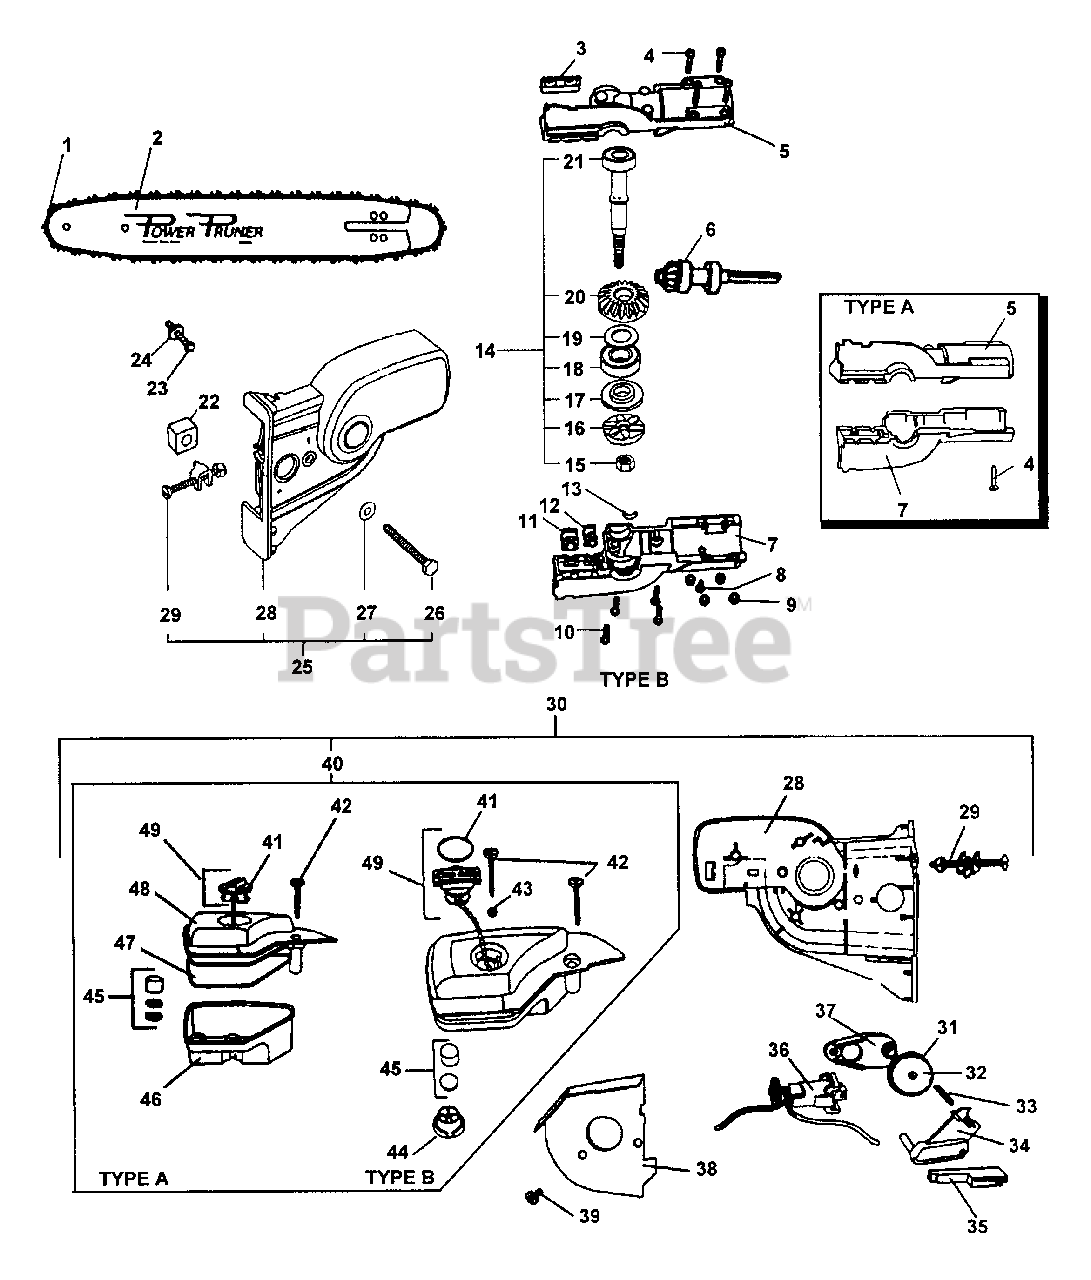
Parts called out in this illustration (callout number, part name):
1	SAWING CHAIN - 90SG -- 10"
2	GUIDE BAR - 10" -- 90VS
4	SCREW, TORX 10-24 UNC 1-1/4
5	CASE, GEAR
6	SHAFT GEAR ASSY
7	CASE, GEAR
8	SCREW
9	NUT, LOCK 10-24 UNC
10	SCREW, TORX
11	SPACER
14	GEAR SHAFT ASSY
15	NUT, HEX
16	SPROCKET DRIVE
17	SPACER, SPROCKET
18	BEARING, BALL 6001 DDU
19	WASHER 12
20	GEAR, BEVEL
21	SHAFT, GEAR
22	SPACER
23	SCREW
24	WASHER 6
25	OILER COVER ASSY
27	WASHER, FLAT
28	COVER, OILER
29	TENSIONER ASSY, CHAIN
30	AUTO-OILER ASSY
32	CAM, OIL PUMP
33	SPRING, COMPRESSION
34	LINK, OILER IDLER
36	AUTO-OILER ASSY
37	LINK, OILER DRIVE
38	PLATE, PROTECTION
39	SCREW 8-32×1/4
40	OIL TANK ASSY
42	SCREW - 8-32×1" - TORX PAN HEAD
44	GROMMET, OIL
45	FILTER, OIL
47	O-RING
49	CAP, OIL
